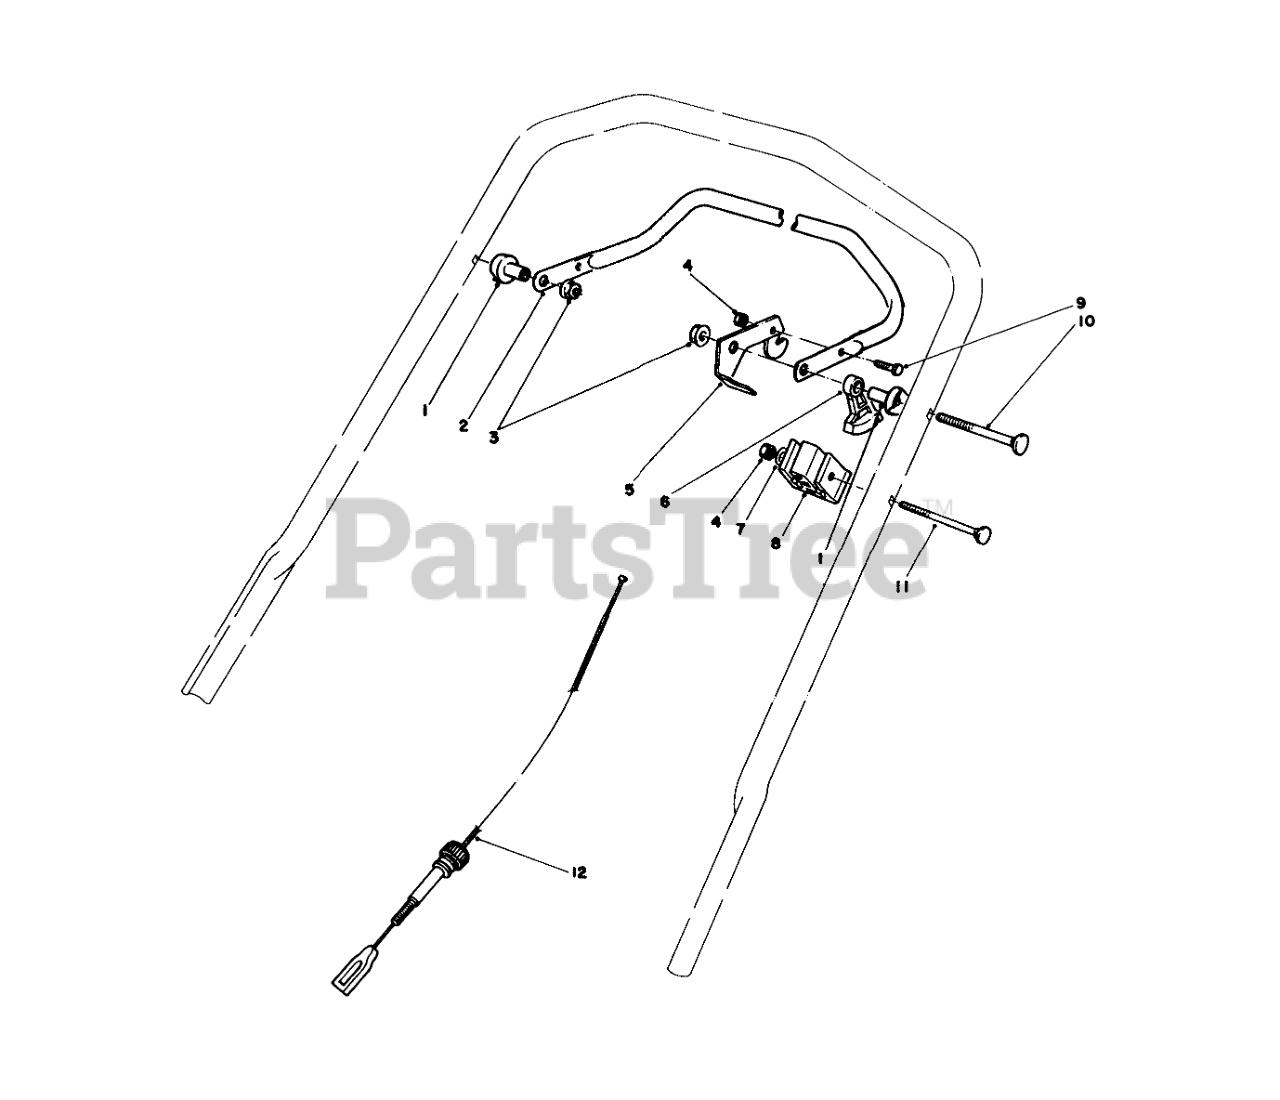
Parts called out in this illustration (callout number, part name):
1	SPACER-SUPPORT
2	Bar-Control
3	NUT-LOCK, NI
4	NUT-LOCK, NI
5	CONTROL LEVER
6	LEVER-TRACTION
7	WASHER-FLAT
8	SUPPORT-CABLE
9	SCREW-HH
10	5/16-18 X 2 HNDLE SCREW
11	HANDLE SCREW
12	CABLE-TRACTION
